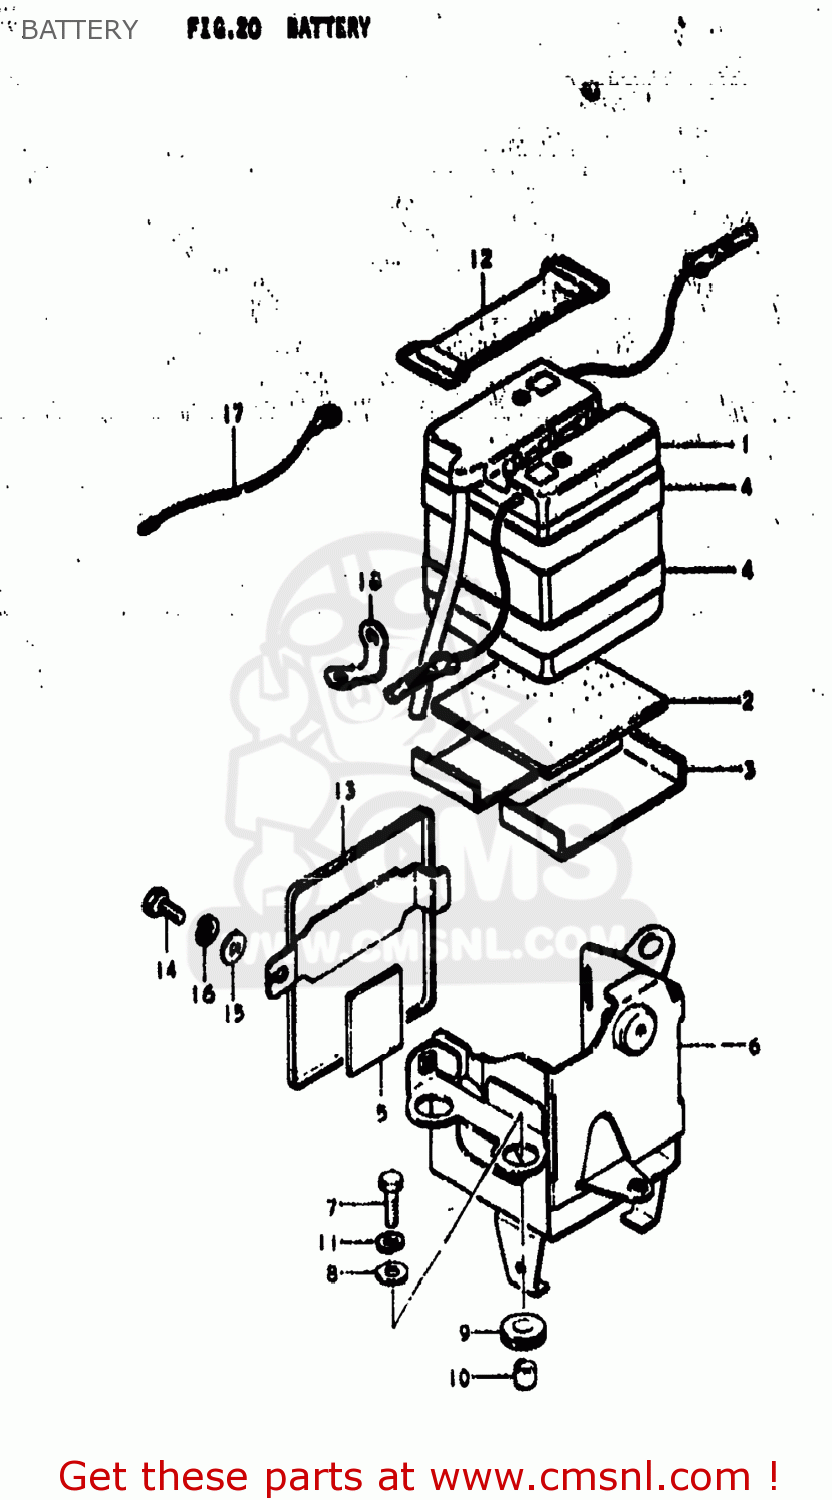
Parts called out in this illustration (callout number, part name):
1	BATTERY ASSY(6N4-2A4.2AH)
2	CUSHION,BATTERY
3	CUSHION,BATTERY
4	PROTECTOR,BATTERY
5	PROTECTOR,BATTERY
6	HOLDER,BATTERY
7	BOLT
8	WASHER (6.5X20X1.2)
9	CUSHION
10	SPACER (7X9X7)
11	LOCK WASHER
12	BAND
14	SCREW(6X10)
15	WASHER
16	LOCK WASHER
17	LEAD WIRE
18	CLAMP
